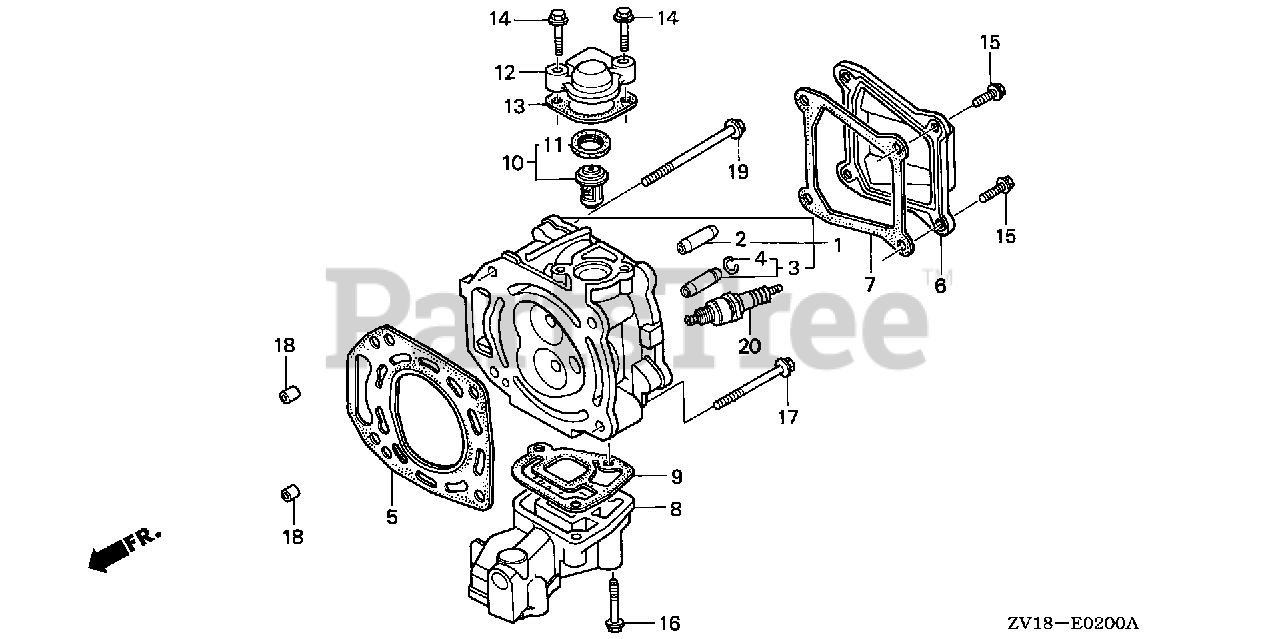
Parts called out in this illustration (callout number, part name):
1	CYLINDER HEAD *NH8* (DARK GRAY)
2	GUIDE, VALVE (OVER SIZE)
3	GUIDE, EX. VALVE (OVER SIZE)
4	CLIP, VALVE GUIDE
5	GASKET, CYLINDER HEAD
6	COVER, HEAD
7	GASKET, HEAD COVER
8	MANIFOLD, EX. *NH8* (DARK GRAY)
9	GASKET, EX. MANIFOLD
10	THERMOSTAT ASSY.
11	RUBBER, THERMOSTAT
12	COVER, THERMOSTAT *NH8* (DARK GRAY)
13	GASKET, THERMOSTAT COVER
14	BOLT, FLANGE (6X23)
15	BOLT, FLANGE (6X12)
16	BOLT, FLANGE (6X32) (CT200)
17	BOLT, FLANGE (8X60)
18	PIN, DOWEL (10X16)
19	BOLT, FLANGE (8X90)
20	SPARK PLUG (W16EPR-U)
20	SPARK PLUG (BPR5ES) (NGK)
20	SPARK PLUG (W16EPR-U) (DENSO)
